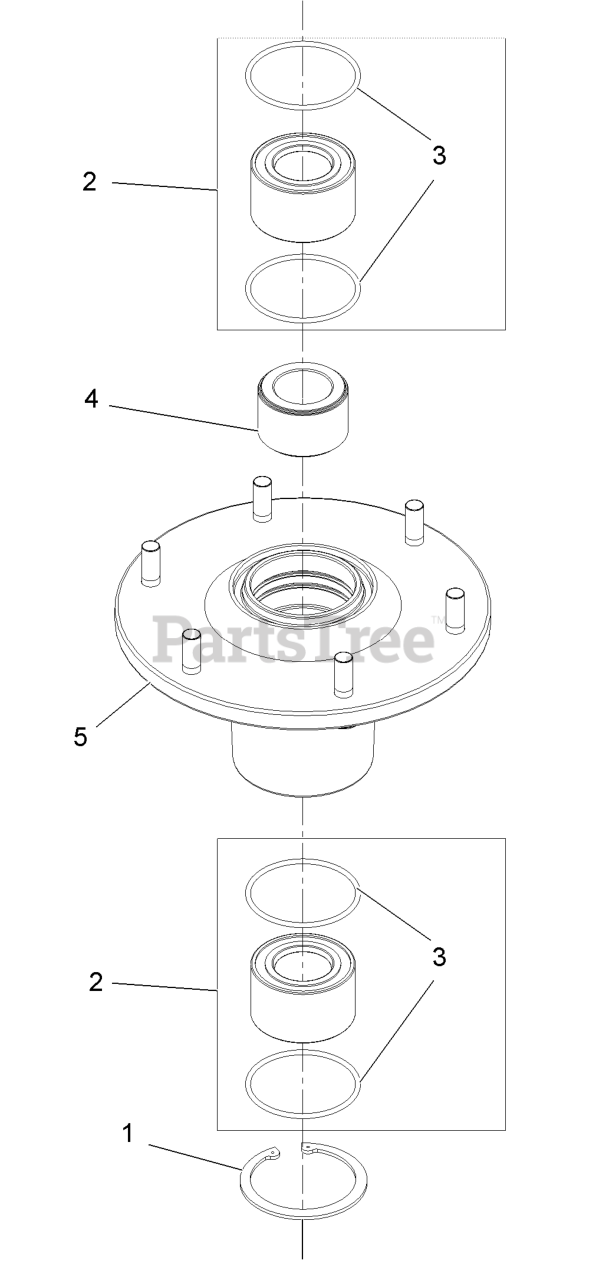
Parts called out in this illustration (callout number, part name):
1	Ring-Retaining
2	Asm, Bearing W/O-Rings
4	Spacer, Bearing
5	Asm, Housing W/Studs
